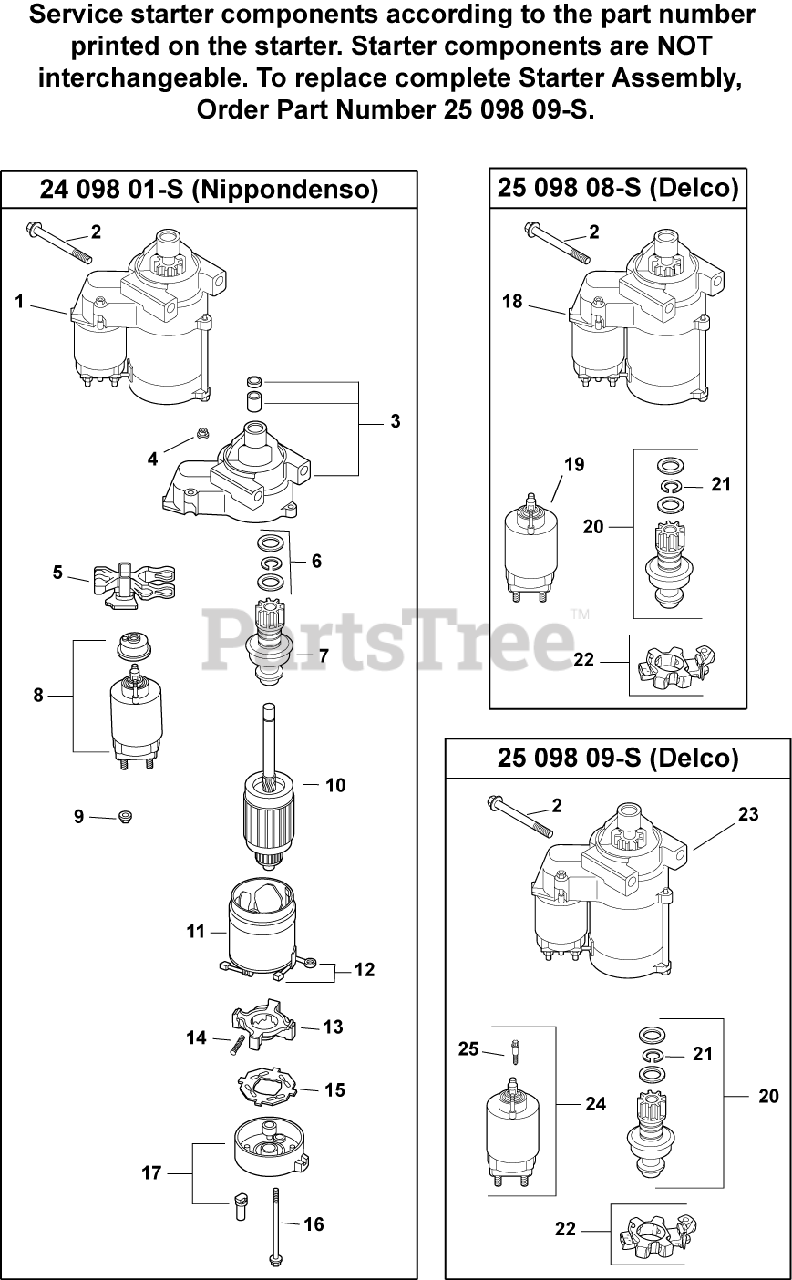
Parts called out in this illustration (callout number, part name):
2	SCREW - USE M-851080-S
3	DRIVE, END CAP
5	LEVER, DRIVE
6	KIT, STARTER REPAIR
7	DRIVE PINION
10	ARMATURE - (#DSC)
11	FRAME W/BRUSHES - DISCONTINUED
12	BRUSH HOLDER
13	BRUSH & SPRING KIT
14	SPRING, BRUSH
15	INSULATOR
16	THRU BOLT
17	COMMUTATOR, END CAP - DISCONTINUED
18	STARTER, SOLENOID SHIFT-USE 25 098 11-S
20	KIT, STARTER PINION
21	RING, RETAINING
22	KIT, BRUSH HOLDER
23	STARTER, SOLENOID SHIFT-USE 25 098 11-S
24	KIT, SOLENOID
25	SCREW, EXTERNAL TORX HEAD
